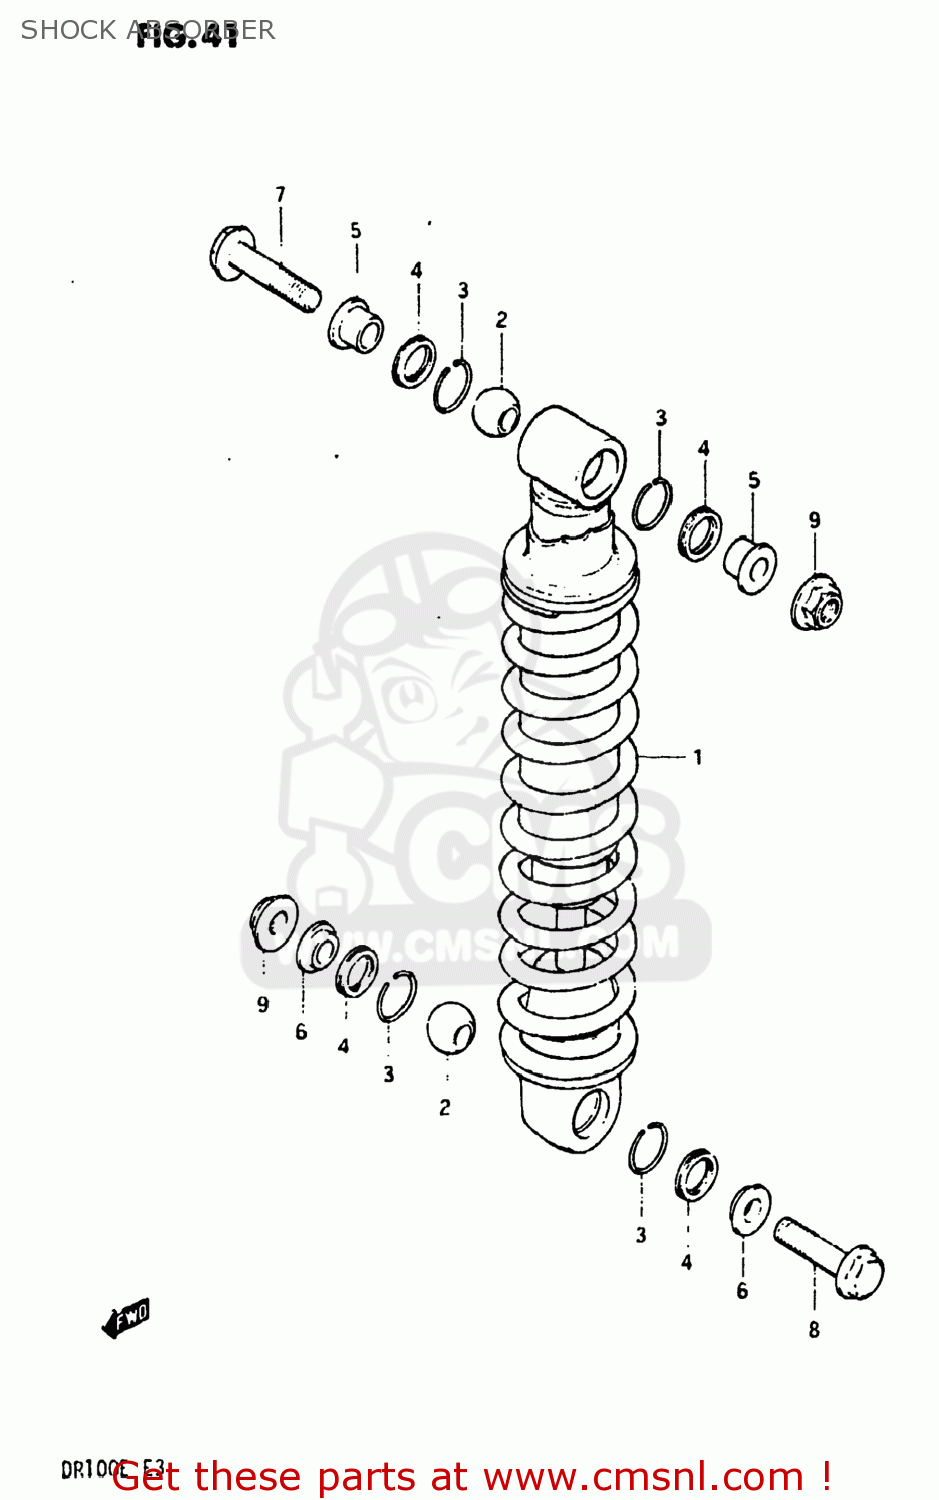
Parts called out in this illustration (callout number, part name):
1	ABSORBER ASSEMBLY,REAR SHOCK
2	BEARING,REAR SHOCK ABSORBER
3	RING
4	DUST SEAL
5	COLLAR,UPR
6	COLLAR,LWR
7	BOLT(10X65)
8	BOLT(10X50)
9	NUT
